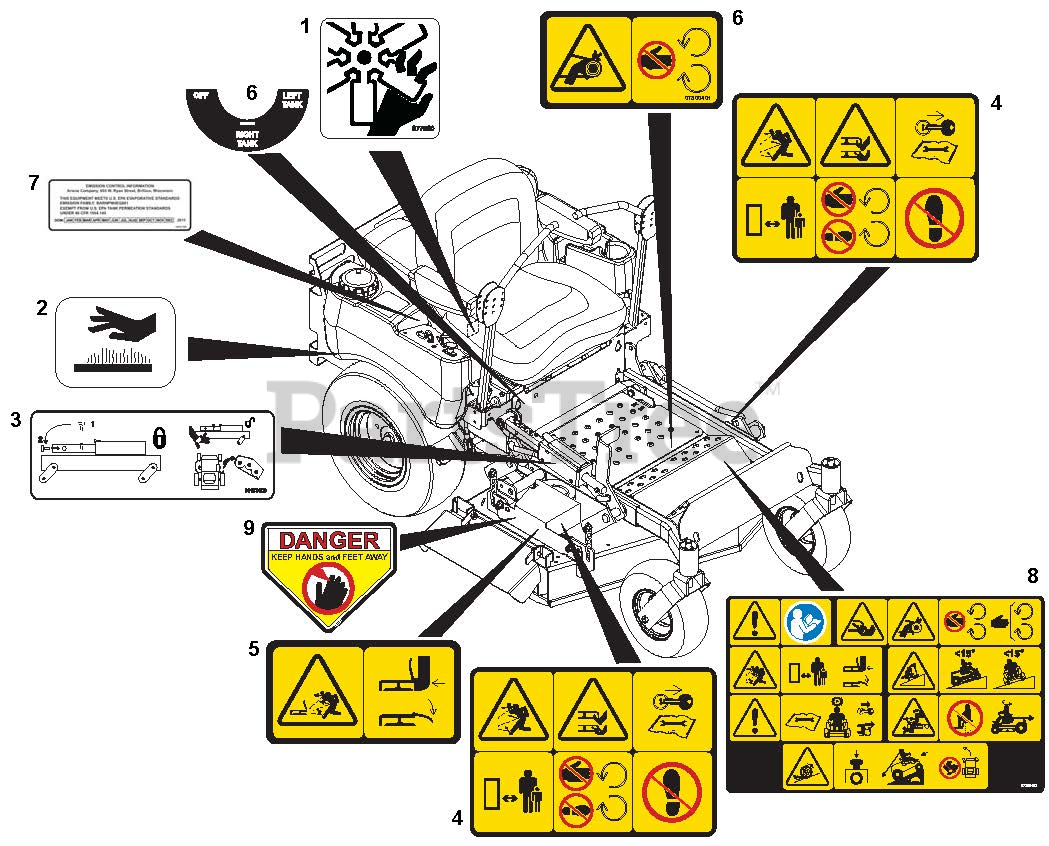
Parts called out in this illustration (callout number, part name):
1	Decal, Danger Fan
2	Decal, Hot Surface
3	Decal, Deck Service
4	Decal, Safety Mower Deck
5	Decal, Safety Deck Guarding
6	Decal, Safety Guarding
7	Decal, EPA
8	Decal, Main Safety Commercial
9	Decal, Danger
